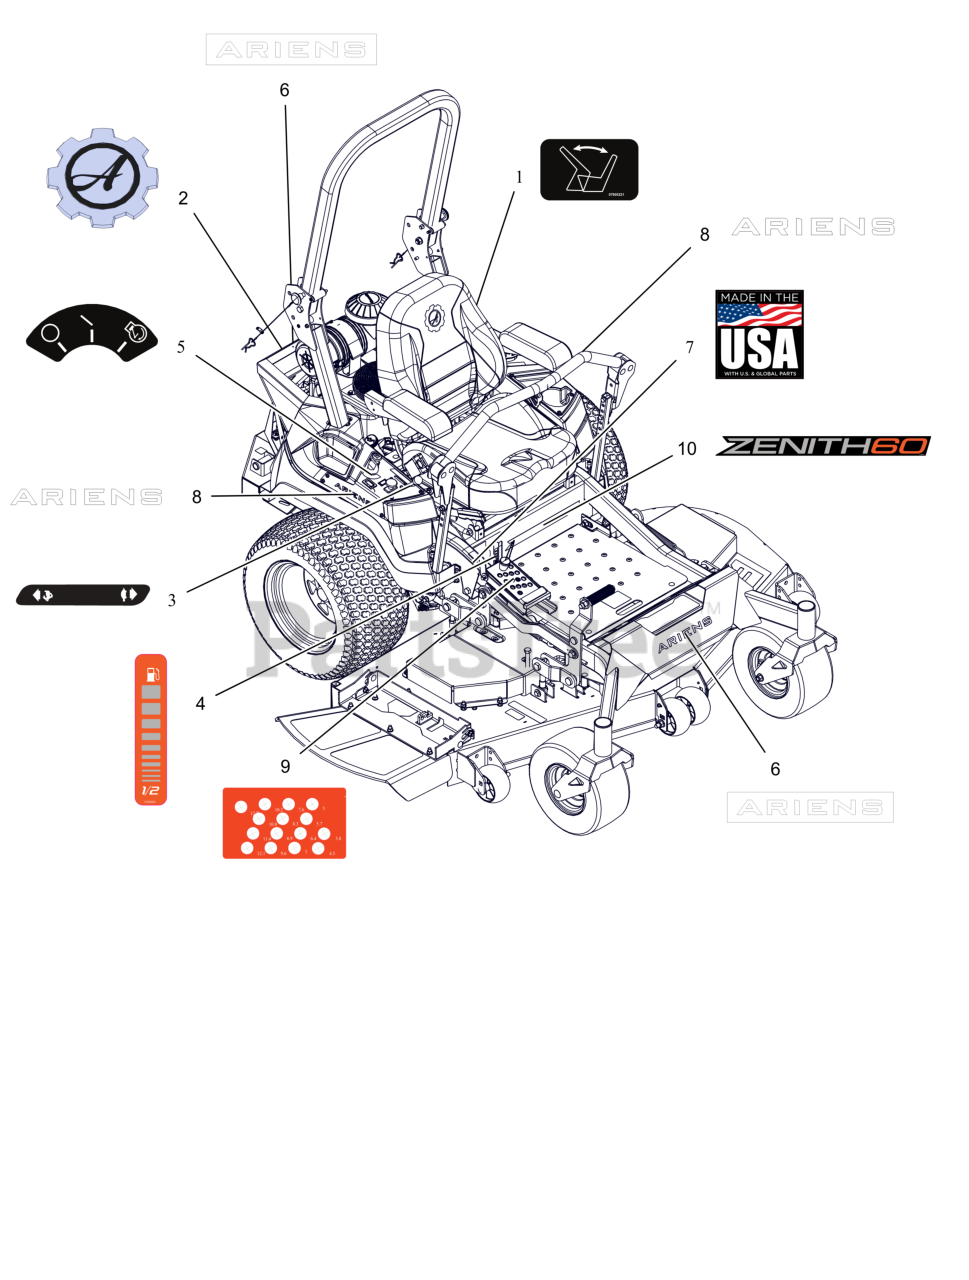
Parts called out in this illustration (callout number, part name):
1	DECAL - SEAT RELEASE
2	DECAL, ARIENS-GEAR BADGE -THK
3	DECAL, DASH DECAL
4	DECAL, ARIENS FUEL LEVEL
5	DECAL, KEYSWITCH
6	DECAL - ARIENS 9.625"
7	DECAL, MADE IN USA
8	DECAL, ARIENS (6.50")
9	DECAL, APEX HOC METRIC
10	DECAL, ZENITH 60
